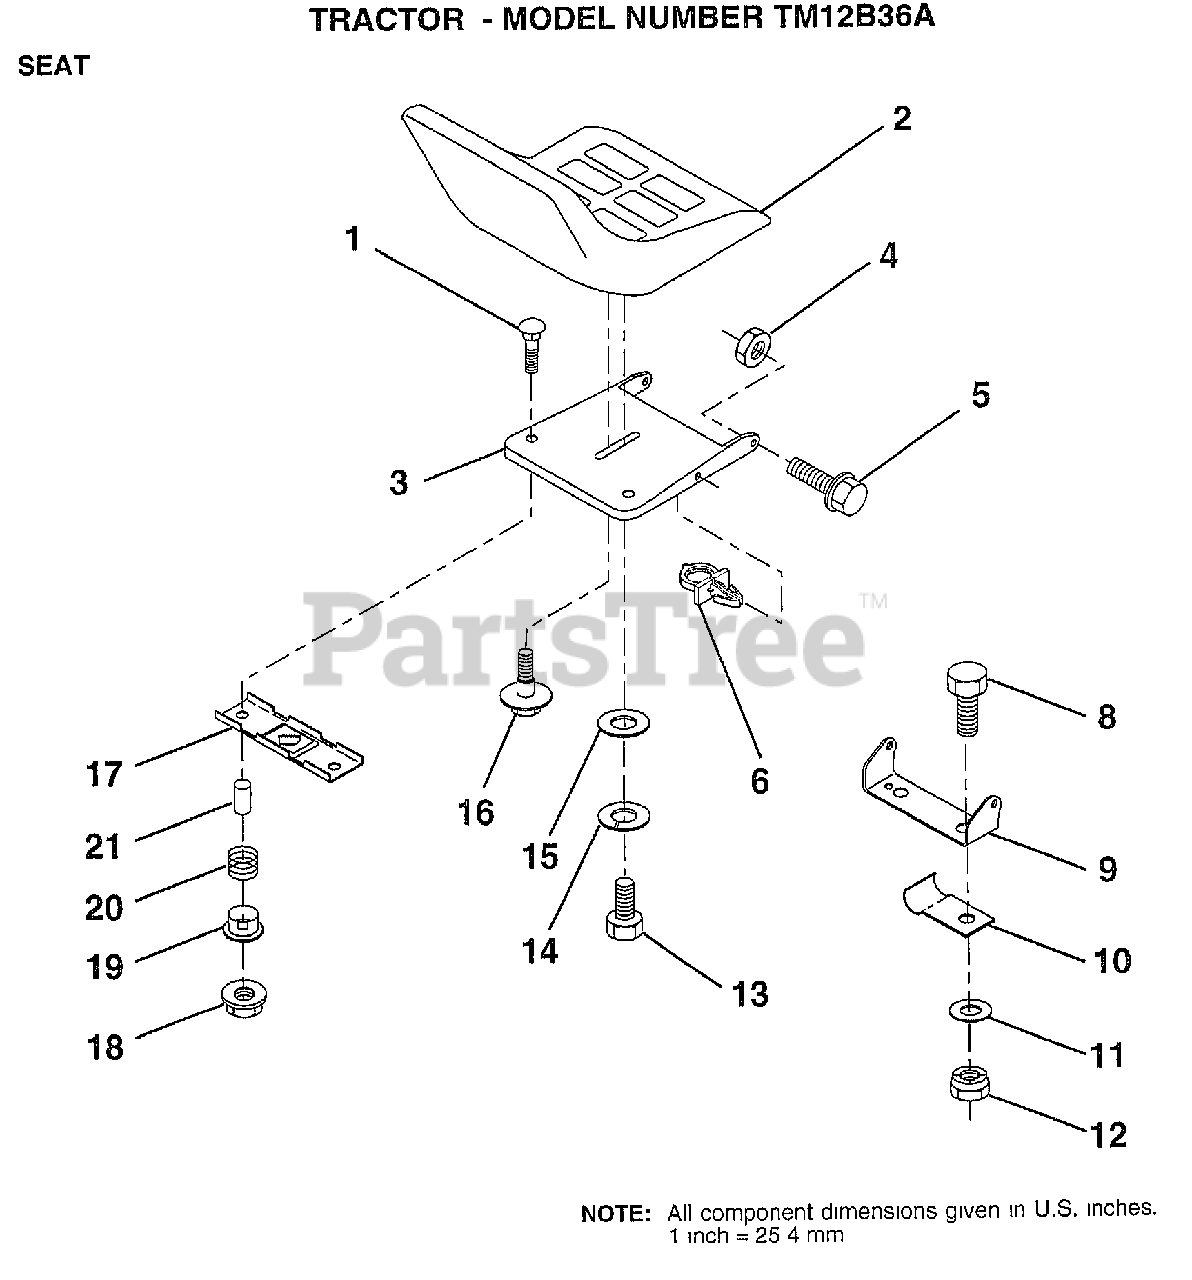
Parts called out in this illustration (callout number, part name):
3	PAN-SEAT
4	NUT
5	"BOLT,SHOULDER"
6	CLIP.PUSH-IN.HING
8	BOLT
9	BRACKET PVT SEAT
10	"CLIP,INSULATOR"
11	WASHER
12	NUT
13	BOLT
14	LOCKWASHER
15	WASHER
16	"BOLT,SHOULDER"
17	BRKT SWITCH
19	BUSHING
20	SPRING
21	SPLIT SPACER
